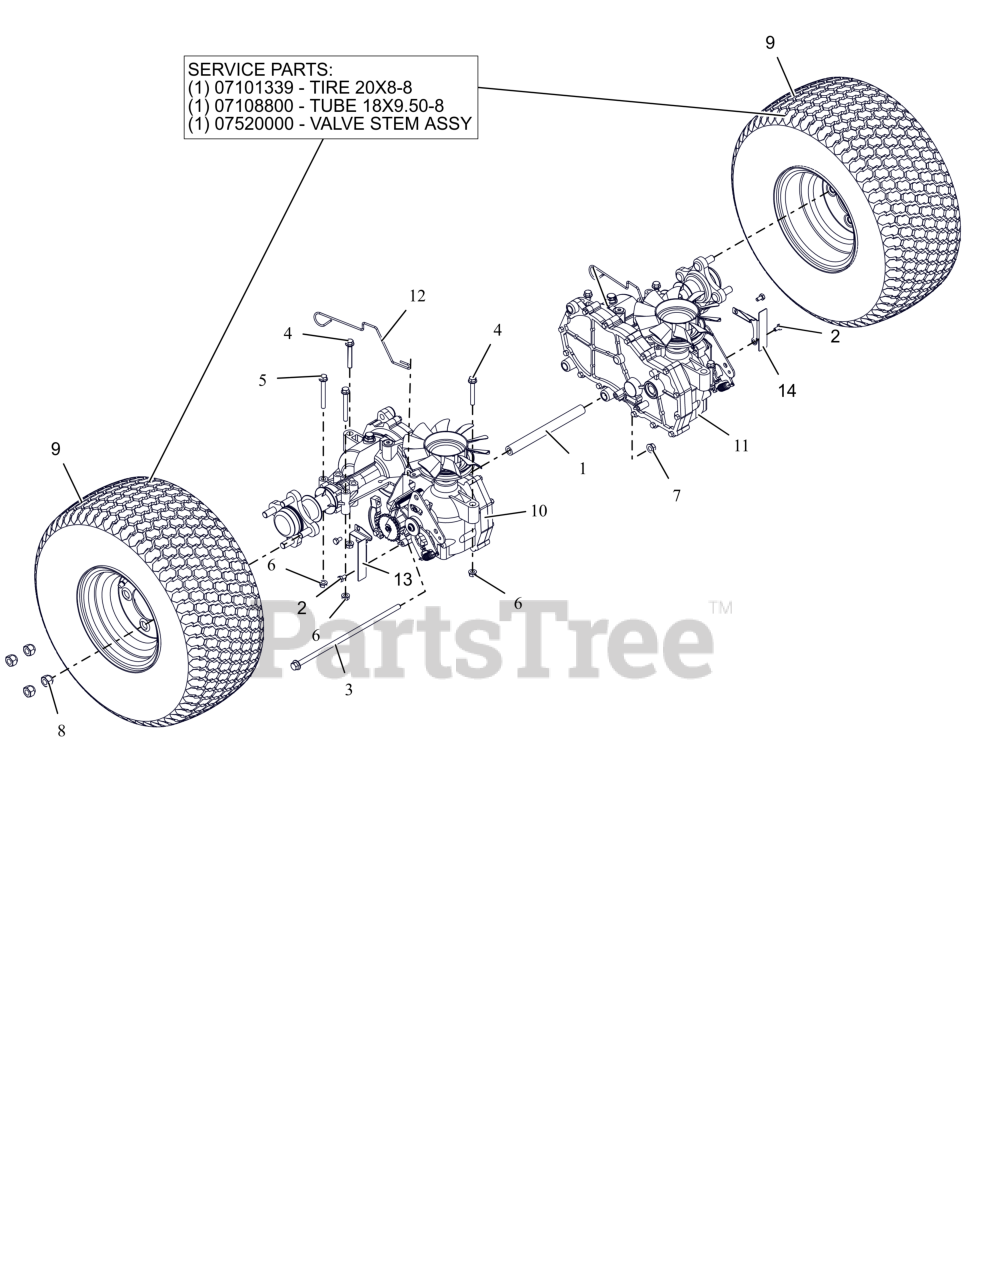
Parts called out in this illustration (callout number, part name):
1	TUBE, TRANSAXLE BRACE 8.18LG
2	BLT,HEX .25-20X.50 G5 ZCC
3	BLT,HEX-FLG .38-16X11.5 G5 ZCC
4	BLT,HEX-FLG .31-18X2.25 G5 ZCC
5	BLT,HEX-FLG .31-18X2.75 G5 ZCC
6	NUT,LK-CTR-FLG .31-18 GF ZCC
7	NUT-LK-CTR-FLG .375-16 GF ZCC
8	NUT, WHEEL .50-20 ZCC
9	ASSM TIRE\WHEEL, 20 X 8 -8
9	LAWN TIRE REAR, 4 PLY K505 20/8.00-8
9	TIRE TUBE 18/6.50/8.50/9.50-8, 20/8.00/10.00-8 4 PLY TR13 STRAIGHT VALVE
9	VALVE STEM ASS'Y
10	TRANSAXLE- EZT-RH
11	TRANSAXLE- EZT - LH
12	WIRE- DUMP VALVE LEVER
13	GUARD, PARKING BRAKE RH,CE (BLACK)
14	GUARD, PARKING BRAKE LH,CE (BLACK)
